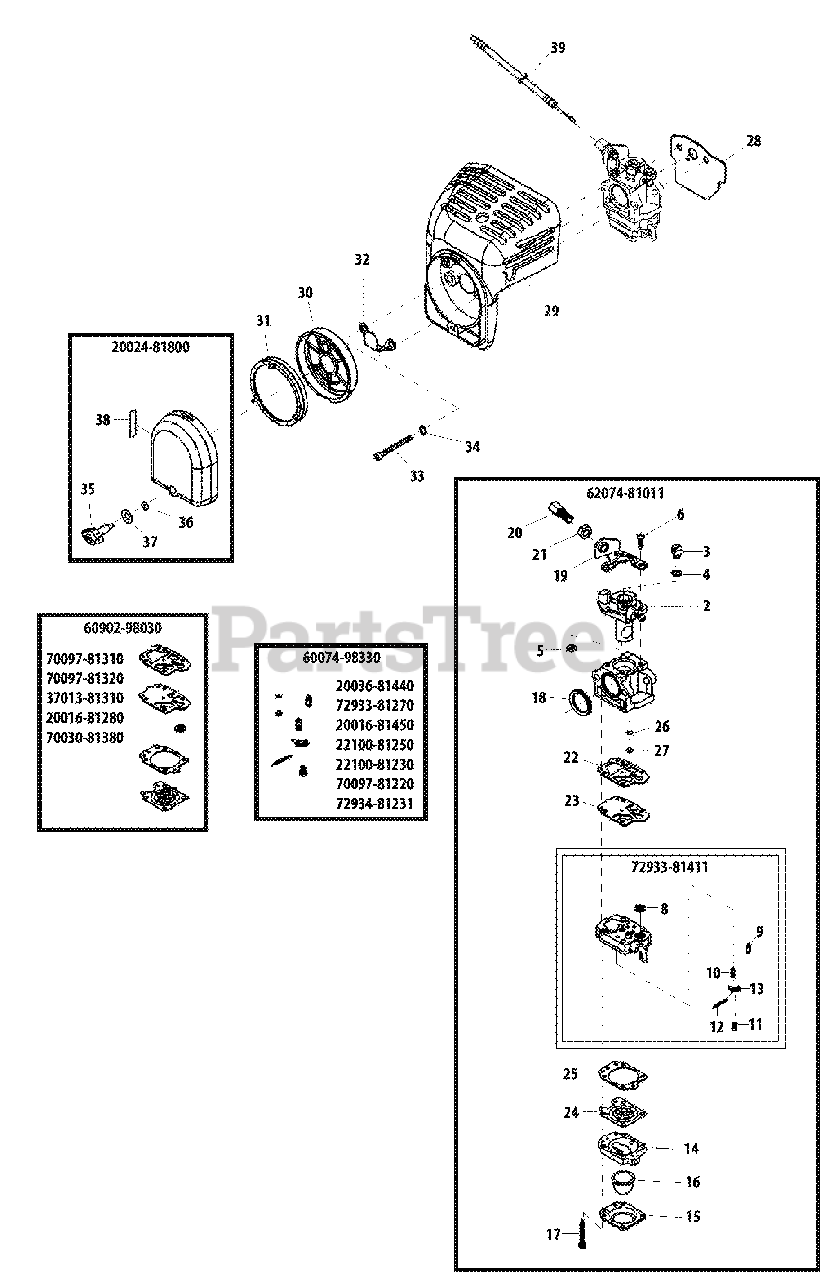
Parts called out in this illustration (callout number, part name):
2	THROTTLE VALVE SET
3	SWIVEL
4	WASHER
5	RING, RETAINING
6	SCREW
8	STRAINER
9	VALVE, INLET NEEDLE
10	SPRING, METERING LEVER
11	SCREW, METERING LEVER PIN
12	PIN, METERING LEVER
13	LEVER, METERING
14	BASE, PURGE
15	RETAINER, PURGE BULB
16	BULB, PURGE
17	SCREW, PUMP COVER
18	SEAL
19	BRACKET, CABLE
20	NUT, CABLE ADJUST
21	NUT
22	GASKET, PUMP
23	DIAPHRAGM, PUMP
24	DIAPHRAGM, METERING
25	GASKET, METERING
26	O-RING
27	JET, MAIN - 37
28	GASKET
29	AIR FILTER CASE ASSY
30	BRACKET, FILTER -- REAR
31	FILTER, AIR - HEAVY DUTY
32	BRACKET
33	SCREW - 5X55
34	LOCKWASHER - 5
35	THUMBSCREW
36	O-RING
37	WASHER - CONICAL
38	LABEL - CHOKE
39	CABLE, THROTTLE
2002481800	AIR FILTER COVER ASSY
6007498330	REPAIR KIT
6090298030	DIAPHRAGM/GASKET KIT
6207481011	CARBURETOR
7293381411	BASE, PURGE
